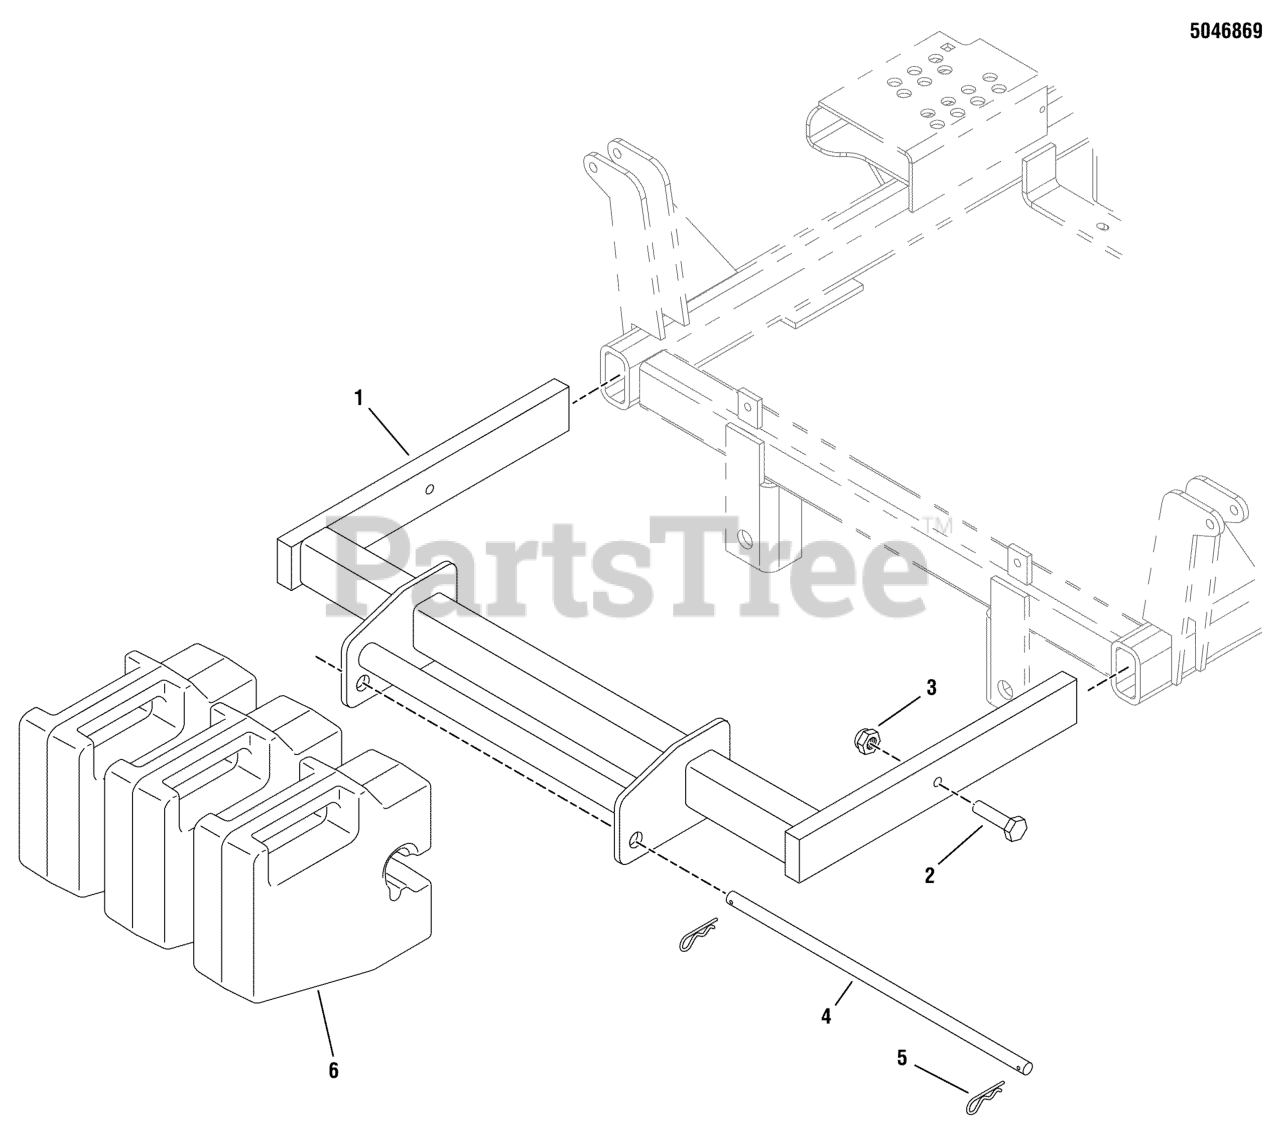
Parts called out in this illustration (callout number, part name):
1	3-BAG WEIGHT RACK WELDMENT
2	BOLT, 3/8-16 X 2, GD5, CZ
3	NUT, 3/8-16 HEX NYLON LOCK
4	ROD, WEIGHT RETAINER
5	PIN, HAIR, .0915 X 1-7/8
6	WEIGHT-QUICK ATTACH 50LB SUITCASE PAINTED
